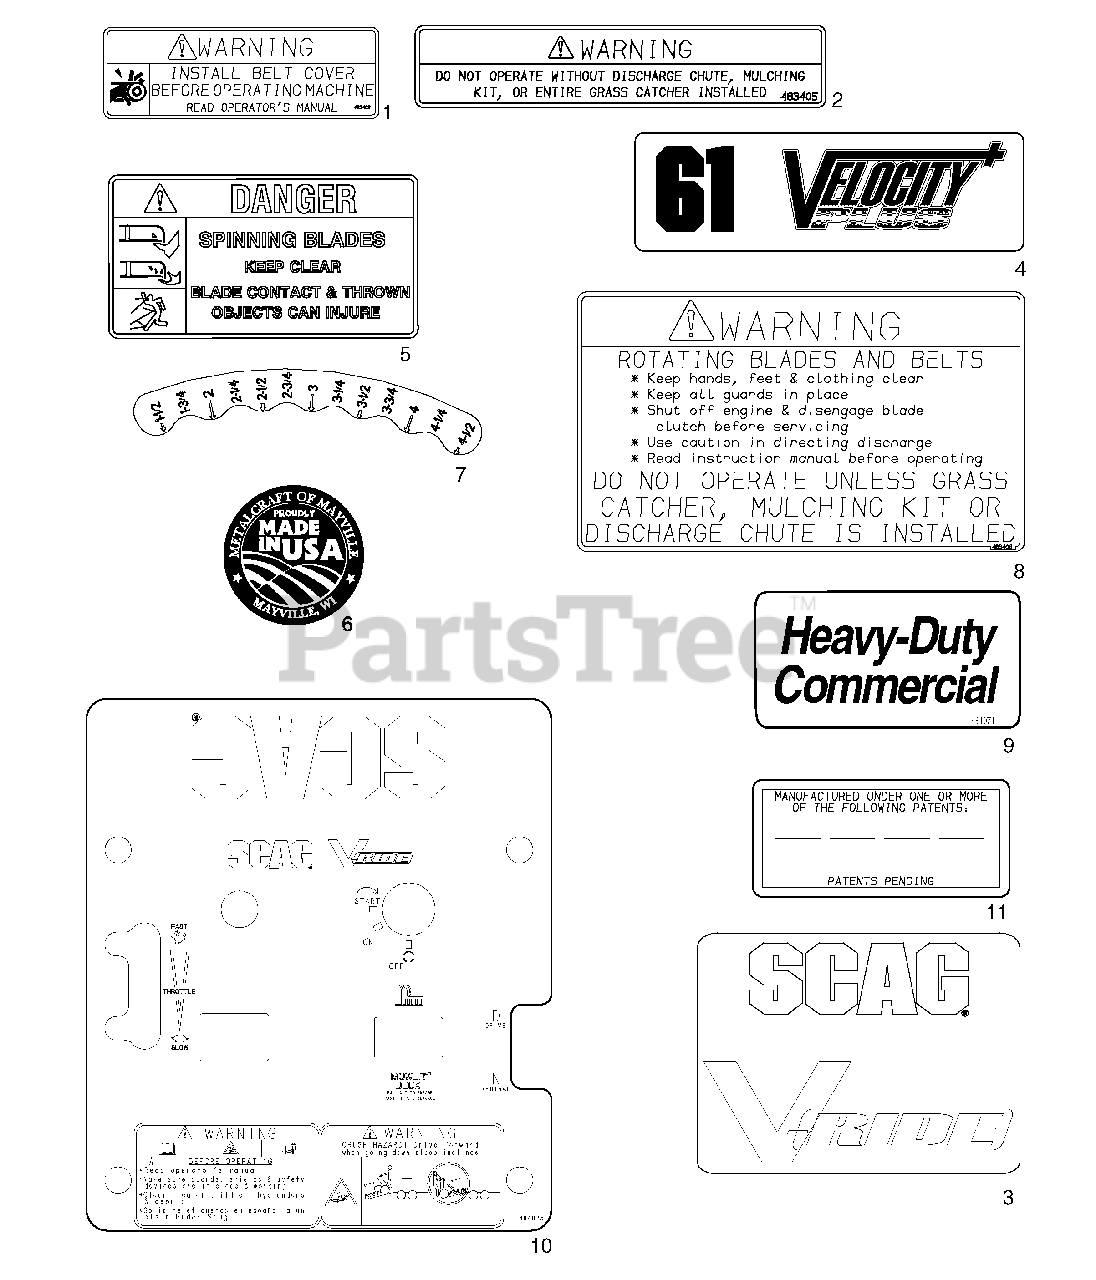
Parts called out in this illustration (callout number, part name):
1	Decal, Warning - Belt Cover
2	Decal, Warning
3	Decal, Belt Cover
4	Decal, 61V
5	Decal, Spinning Blades
6	Decal, Metalcraft - Made in USA
7	Decal, Height-of-Cut
8	Decal, Warning - Knives
9	Decal, Heavy Duty Commercial
10	Decal, Instrument Panel
11	Decal, Patents
